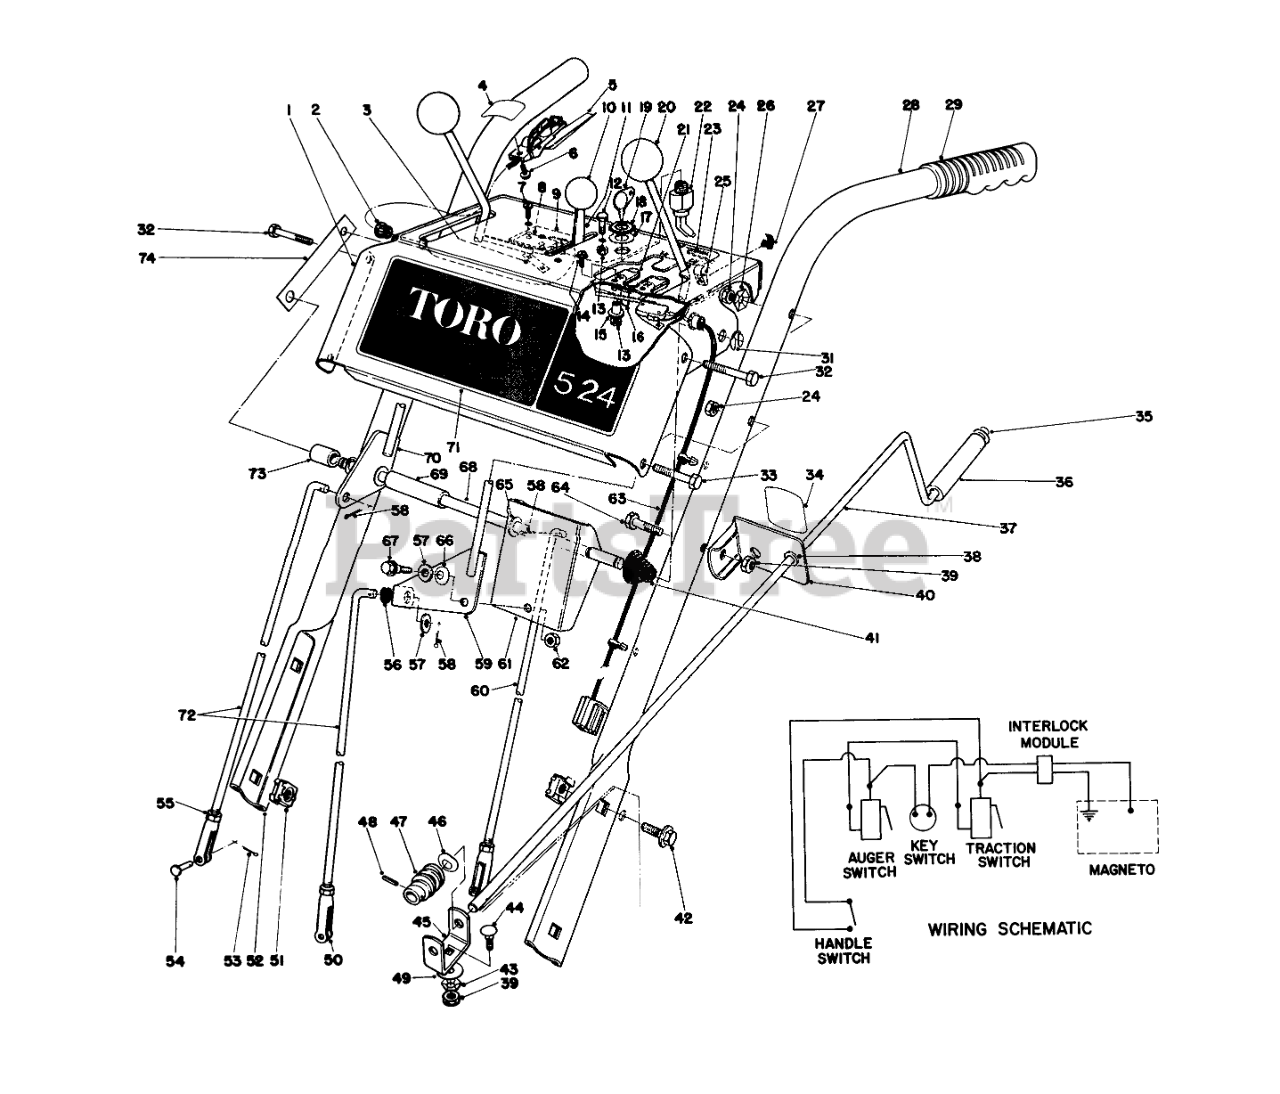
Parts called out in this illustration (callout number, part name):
1	ESCUTCHEON PLT B
2	BUSHING NYLON
3	NUT-SPEED
4	INTERLOCK DECAL
5	INTERLOCK HDLE SWITCH
6	SCREW
7	SCREW-SPH
8	SWITCH-MICRO
9	SWITCH MTG PAD
10	CONTROL KNOB
11	THROTTLE CONTROL
12	HEX HEAD SEMS 10-24X1/2
13	Nut
14	SCREW-SRH
15	INTERLOCK SPACER
16	INTERLOCK SPRING
17	WASHER-TOOTH, INTERNAL
18	NUT-HH
19	Key
21	Slide Interlock
22	Key Switch
23	INSTRUCTION DECAL
24	NUT-LOCK, CONE
25	WIRE CLAMP
26	Washer
27	Mounting Stud
28	LEFT HANDLE
29	Grip Handle
31	RING-CLIP
32	SCREW-HH
33	SCREW-HH
34	CHUTE DECAL
35	RETAINER-PUSH ON
36	GRIP-CONTROL, CHUTE
37	CHUTE CONTROL ROD
38	Bushing
39	NUT-LOCK, NI
40	Chute Control Rod Mounting (Incl. Ref. #34 & 38)
41	CONICAL SPRING
42	SCREW-HHF
43	WASHER-LOCK
44	BOLT-CARR
45	WORM BRACKET
46	WASHER-SPRING
47	GEAR-WORM, CHUTE
48	PIN-SPRING
49	WASHER
50	CLEVIS
51	Retained Nut
52	HANDLE RIGHT
53	PIN-COTTER
54	PIN-CLEVIS
55	NUT-HJ
56	GROMMET-RUBBER
57	WASHER-FLAT
58	PIN-COTTER
59	SHIFT LEVER WA
60	TRACTION CONTROL ROD
61	SHIFT BRACKET
62	NUT-LOCK, CONE
63	WIRE HARNESS INTERLOC
64	SCREW-HH
65	WASHER-FLAT
66	7/16 SPRING WASHER
67	SHOULDER SCREW
68	PIVOT ROD
69	SHIFT LEVER SPACER
70	LEVER WA
71	ESCUTCHEON DECAL
72	SPEED SELECTOR ROD
73	AUGER LEVER SPACER
74	ESCUTCHEON SUPT STRAP
